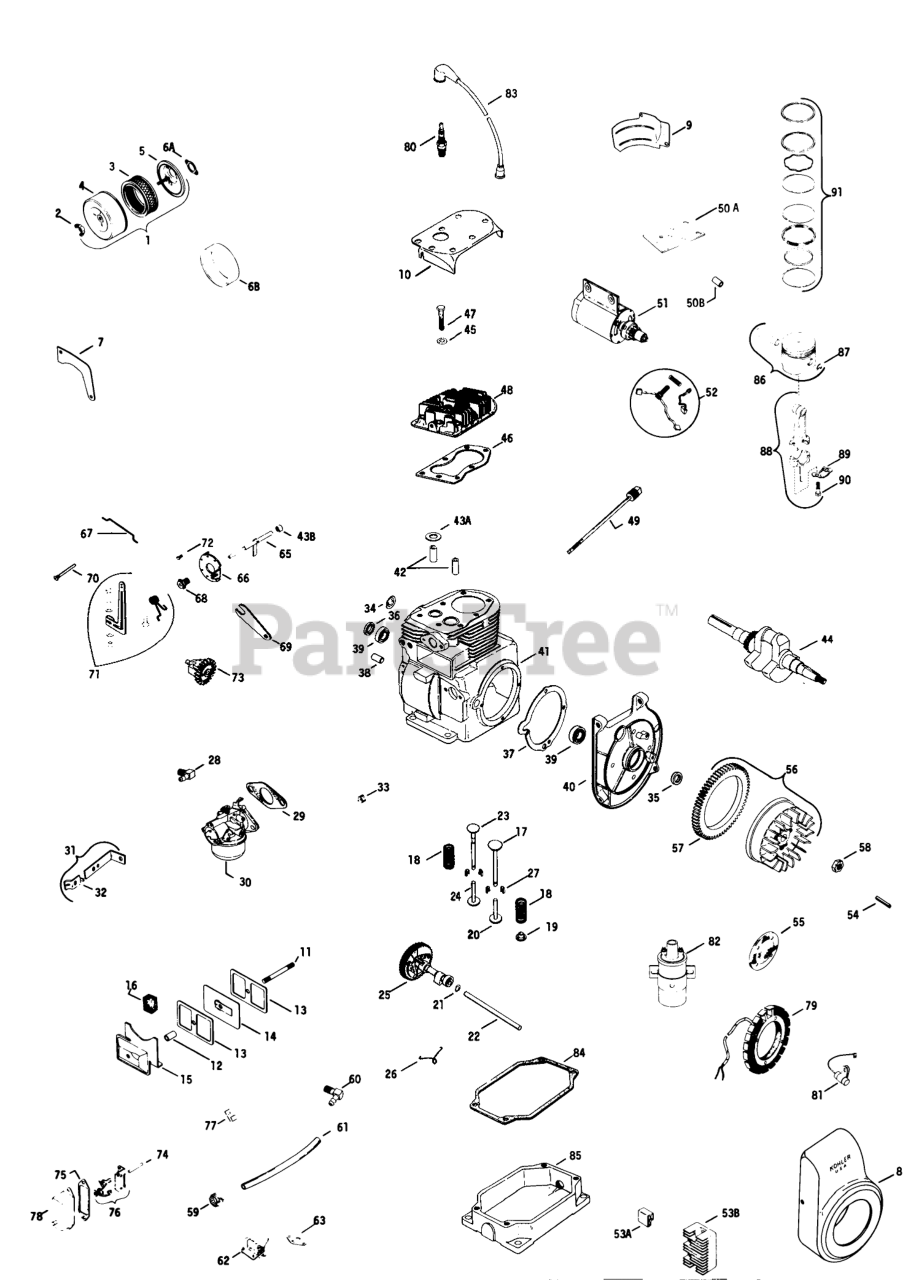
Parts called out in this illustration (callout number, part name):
1	Cleaner, air-assembly
2	Nut-Wing
3	Element, Air Cleaner
4	Valve-Needle, Float
5	Base, Air Cleaner
6A	Gasket
6B	Element, Pre-Cleaner
7	Baffle side air
8	Housing, blower
9	Baffle cylinder
10	Baffle, Head
11	Stud valve cover
12	Seal
13	Gasket-Valve Cover
14	Breather
15	Cover, Valve
16	Filter
17	Valve-Intake
18	Spring, Valve
19	Retainer-Spring
20	Tappet, Valve
21	Spacer camshaft .005
21	Spacer, Camshaft.010
22	Pin, Camshaft
23	Valve, exhaust
24	Tappet-Exhaust Valve
25	Kit, camshaft
27	Keeper, Valve
28	Elbow
29	Gasket-Carburetor
30	Carburetor-assembly
30	Repairkit
31	Bracket, choke
32	Clip
33	Plug
34	Plug
35	Seal Front Oil
36	Seal Rear Oil
37	Gasket
38	Pin-Dowel
39	Ball Bearing
40	Plate, Bearing
41	Block, cylinder-assembly (Use B-234989 Miniblock)
42	Guide-Valve
43A	Insert
43B	Bearing
44	Crankshaft
45	Washer
46	Gasket, head
47	Screw, H.C. 5/16-18 x 1-1/2
48	Head, Cylinder
49	Dipstick
50A	Bracket, coil
50B	Spacer
51	Starter
52	Kit, Brush & Spring
53A	Connector
53B	Regulator
54	Key
55	Screen, grass
56	Flywheel
57	Gear Ring
58	Nut
59	Clamp
60	Elbow
61	Line, Fuel
62	Pump, fuel
63	Gasket, fuel pump
65	Shaft-Governor Cross
66	Disc, regulating
67	Link-Governor
68	Bushing Governor
69	Bracket, speed control
70	Pin-GovemorStop
71	Lever, Governor
72	Pin
73	Gear, Governor
74	Rod, Breaker
75	Gasket, Cover
76	Breaker
77	Clip
78	Cover breaker
79	Stator
80	Spark plug
81	Condenser
82	Coil
83	Kit, Hi-Tension
84	Gasket, pan
85	Pan, oil
86	Piston-assembly--Std. (Includes pin & retainers)
86	Piston-assembly--.003 (Includes pin & retainers)
86	Piston-assembly--.010 (Includes pin & retainers)
86	Piston-assembly--.020 (Includes pin & retainers)
86	Piston-assembly--.030 (Includes pin & retainers)
87	Retainer, Pin
88	Rod, Connecting Std.
88	Rod, Connecting .010
89	Lock, Conn. Rod
90	90A9-5/66734 SENSAT
91	Ring Set Std.
91	Ring Set .010
91	Ring Set.020
91	Ring Set .030
91	Gasket Set
91	Service Engine
91	Miniblock
